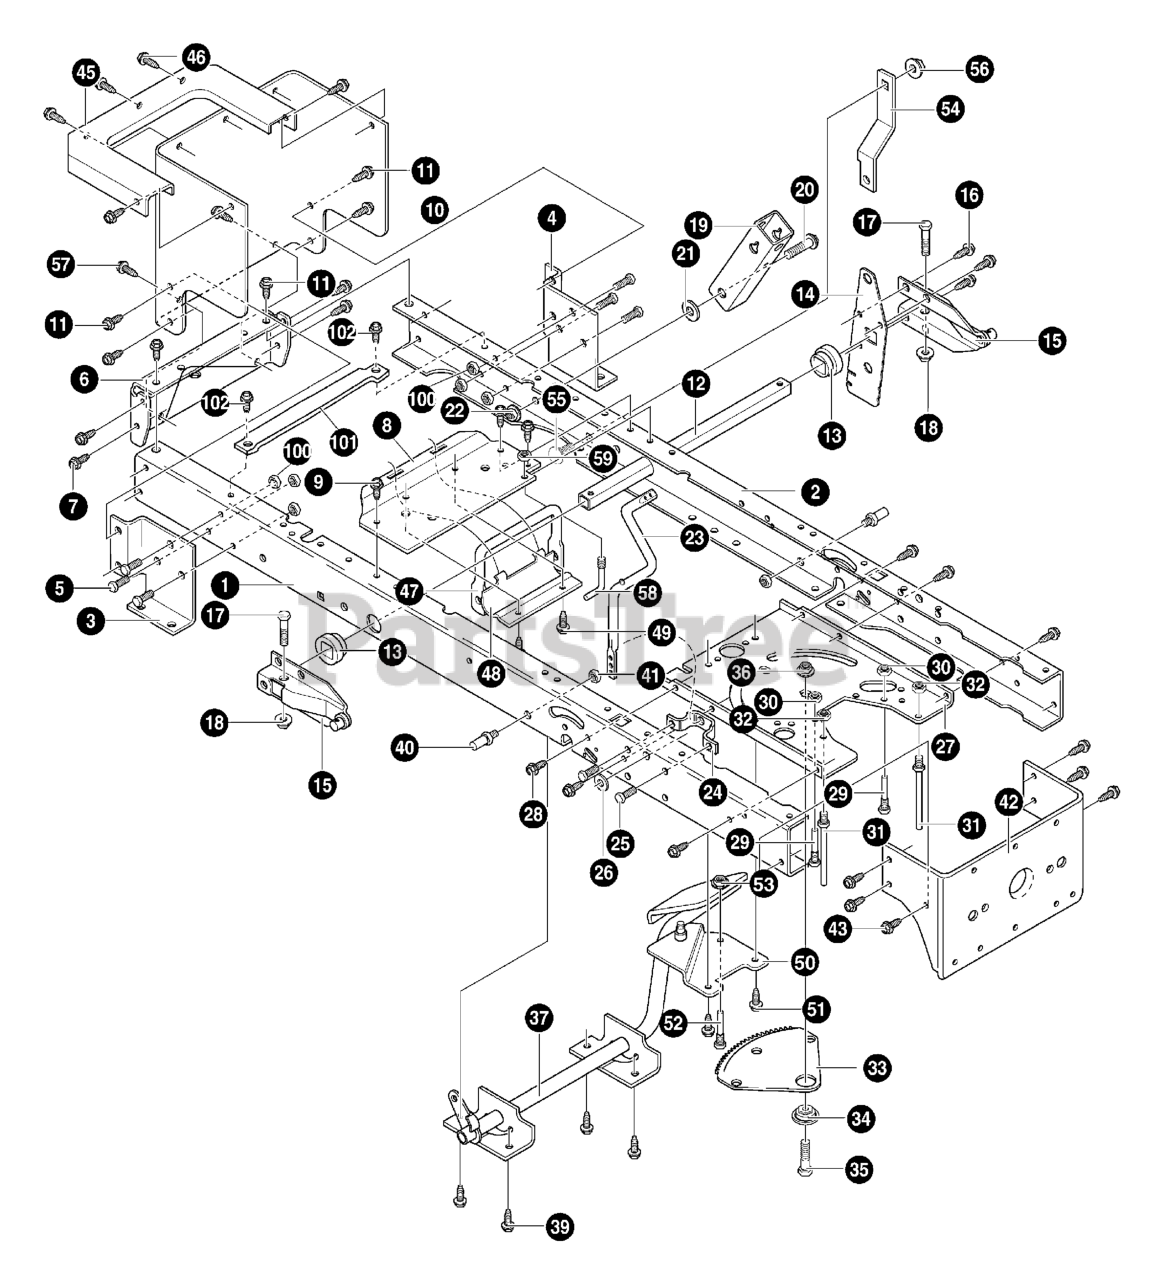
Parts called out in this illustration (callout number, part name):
1	RAIL-FRAME RH SHORT
2	RAIL-FRAME LH SHORT
3	BRACKET, RIGHT TRANSAXLE
4	BRACKET, LEFT TRANSAXLE
8	BRACKET, IDLE
10	PLATE, REAR
12	TUBE, LIFTER
13	BUSHING, LIFT TUBE
14	PLATE, LIFT ARM
15	LEVER, LIFT ARM
18	LOCKNUT, FLANGE
19	BRACKET, PIVOT
22	NUT
23	CRANK, PTO
24	BRACKET, BELL CRANK
26	WASHER, FLAT
27	PLATE, STEERING
29	SCREW, GUIDE
30	NUT
31	SCREW, GUIDE
32	NUT
33	GEAR, SECTOR
34	BEARING, SECTOR GEAR
35	CAPSCREW, Hex Head, 5/16-18 x 1
36	NUT, HKEPS
37	PEDAL
40	PIN, THREADED SHOULDER
41	NUT, 3/8-16
42	BRACKET, REAR HANGER
45	PLATE, REAR SEAT
46	SCREW
47	ROD, TRUNNION YOKE
48	CLAMP, TRUNNION
50	IDLER, INTERMEDIATE
52	SCREW, GUIDE
53	NUT
54	BRACKET, Torque Strap, LH
55	BOLT
56	NUT
57	BOLT
58	SCREW, GUIDE
59	NUT
100	NUT
101	BATTERY, SUPPORT
